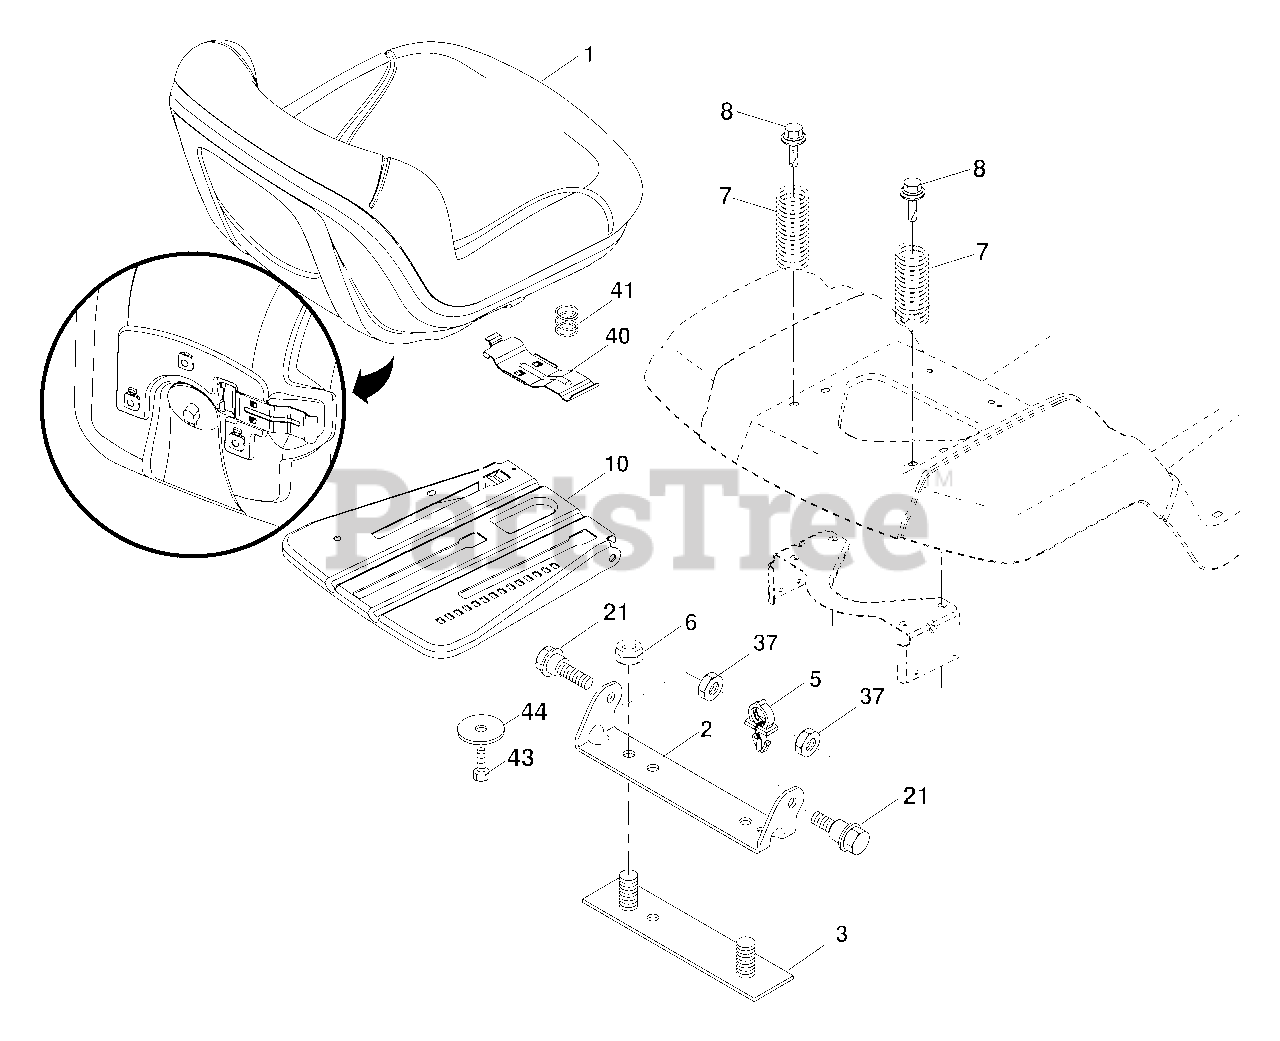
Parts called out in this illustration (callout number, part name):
1	Seat
2	Bracket Pivot Fender
3	Strap, Asm Fender
5	Clip, Push In, Hinged
6	Nut, Lock W/Ins. 3/8-16 unc
7	Spring, Seat Cprsn
8	Bolt 5/16-18 uncx 3/4 w/Sems
10	Pan, Seat
21	Bolt, Shoulder 5/16-18
37	Nut, Lock 5/16-18 unc
40	Handle Slide Seat
41	Spring Latch Seat
43	Bolt Fin Hex 3/8-16 unc x 3/4
44	Washer 13/32 x 2-3/8 x 12 Ga.
